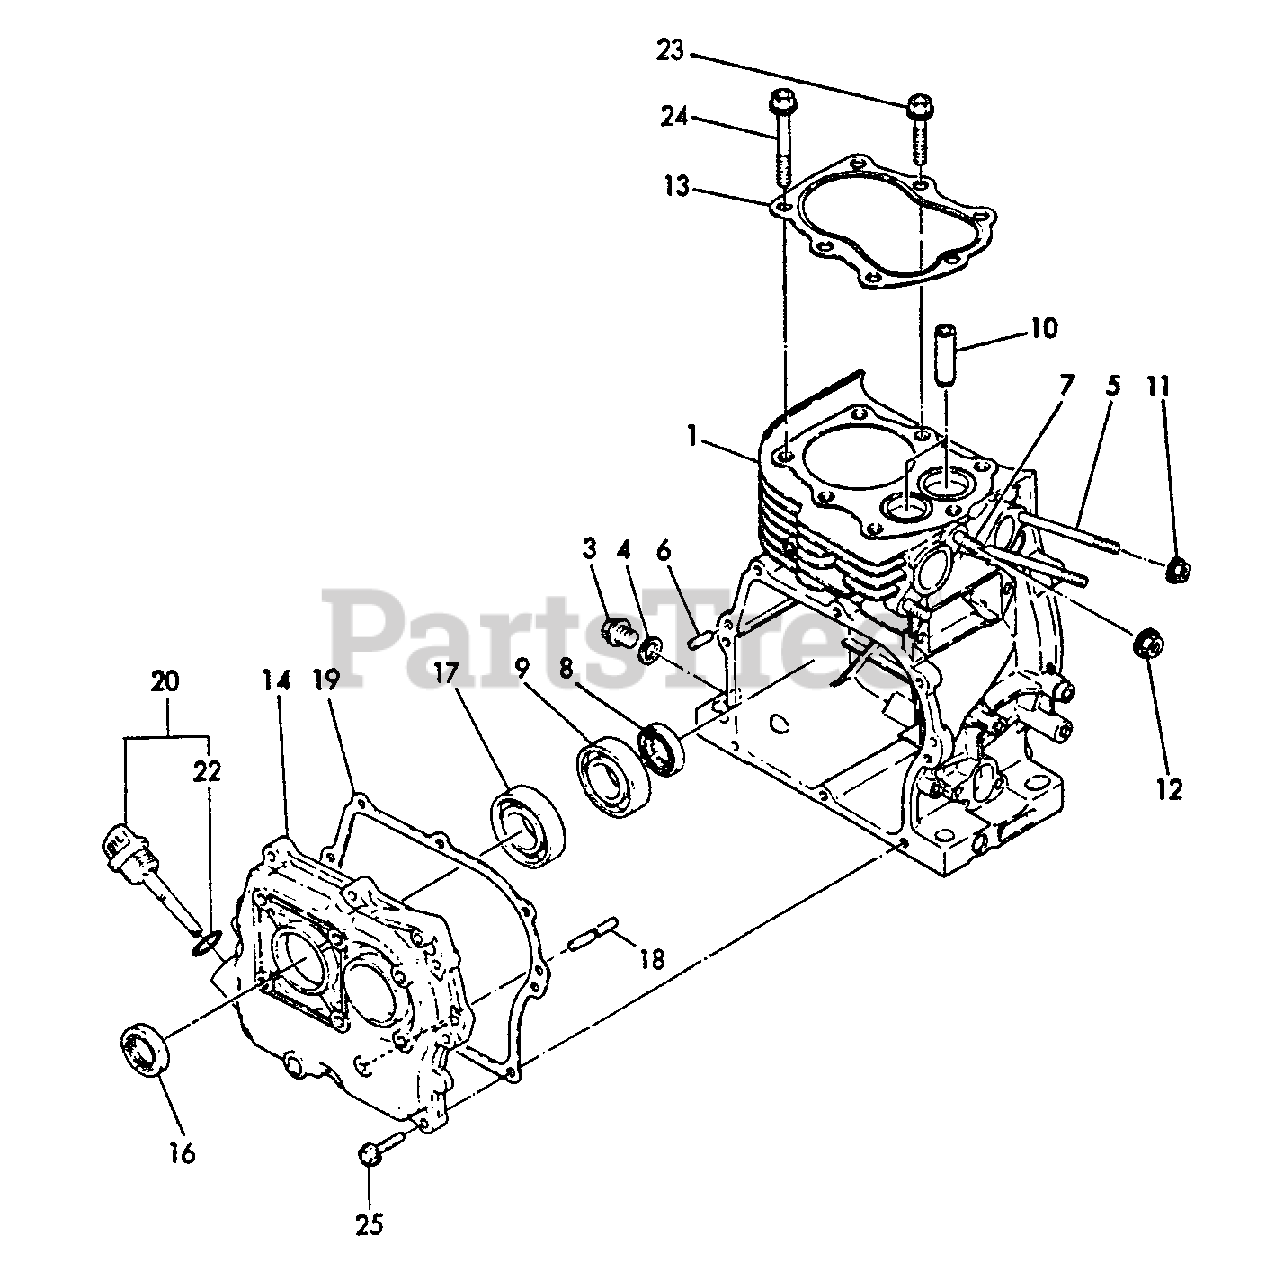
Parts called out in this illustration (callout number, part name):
1	CYLINDER BLOCK SET
3	PLUG, DRAIN
4	GASKET
5	BOLT - 6X70
6	PIN - 6X16
7	STUD - 8X18 -- PLATED
8	SEAL, OIL
9	BEARING, BALL - 6205C3
10	GUIDE, VALVE - EXHAUST
11	NUT - 6 -- FLANGE
12	NUT - 8
13	GASKET, CYLINDER
14	SIDE COVER ASSY
16	SEAL, OIL
17	BEARING, BALL - 6205C3
18	SHAFT, GOVERNOR
19	GASKET, SIDE COVER
20	CAP ASSY
22	O-RING - 18
23	BOLT - 8X39
24	BOLT - 8X65
25	BOLT - 6X25
